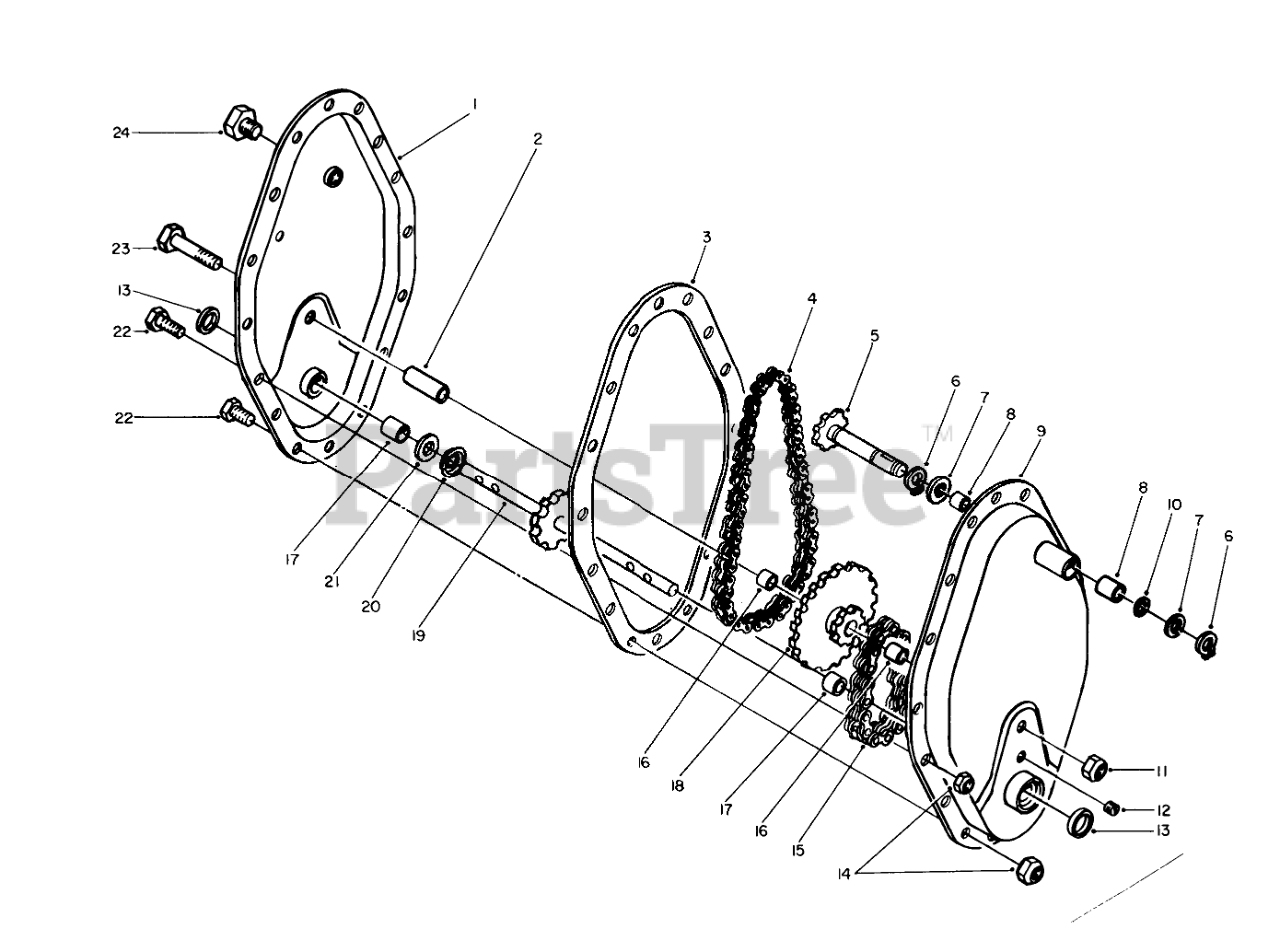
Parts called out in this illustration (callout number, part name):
1	Chain Case-R.H. w/Bearings
2	Idler Sleeve
3	Gasket
4	Chain-Upper
5	Input Shaft
6	Retaining Ring
7	Washer
8	BEARING-NEEDLE
9	Chain Case-L.H. w/Bearings
10	Seal
11	NUT-LOCK, CONE
13	Seal
14	NUT-LOCK, CONE
15	Chain-Lower
16	NEEDLE BRG
17	Bearing
18	Sprocket (Incl. Ref. #16)
19	Tine Shaft
20	Spacer Cup
21	Shim-Gear
22	SCREW-HH
23	Capscrew
24	SCREW-HH
